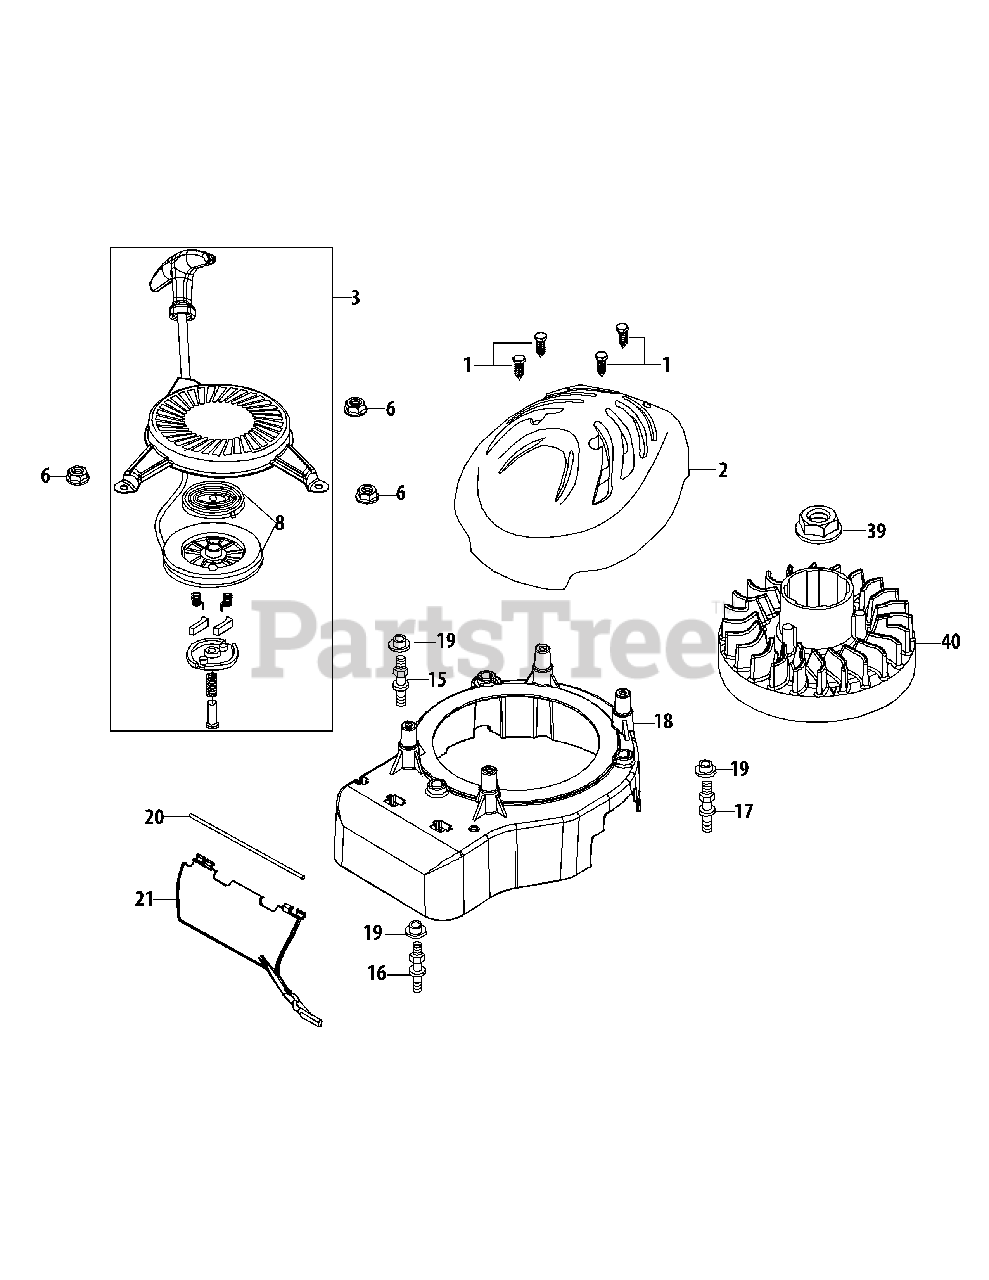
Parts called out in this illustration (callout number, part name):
1	Self-Tapping Bolt, Hilo #12-16 X 1.00"
2	Outer Shroud (Model Specific)
3	Recoil Starter Assembly
6	Nut M6X10Mm Starter/Carb/Muff
8	Recoil Spring and Pulley Ass'y
15	Stud Left/Black/Wh Zinc
16	Stud Front/Unmarked/Wh Zinc
17	Stud Right/White/Wh Zinc
18	Inner Shroud
18	Inner Shroud Assy (Incl.19)
19	Engine Shroud Spacer
20	Air Vane Shaft
39	Flywheel Nut M14
